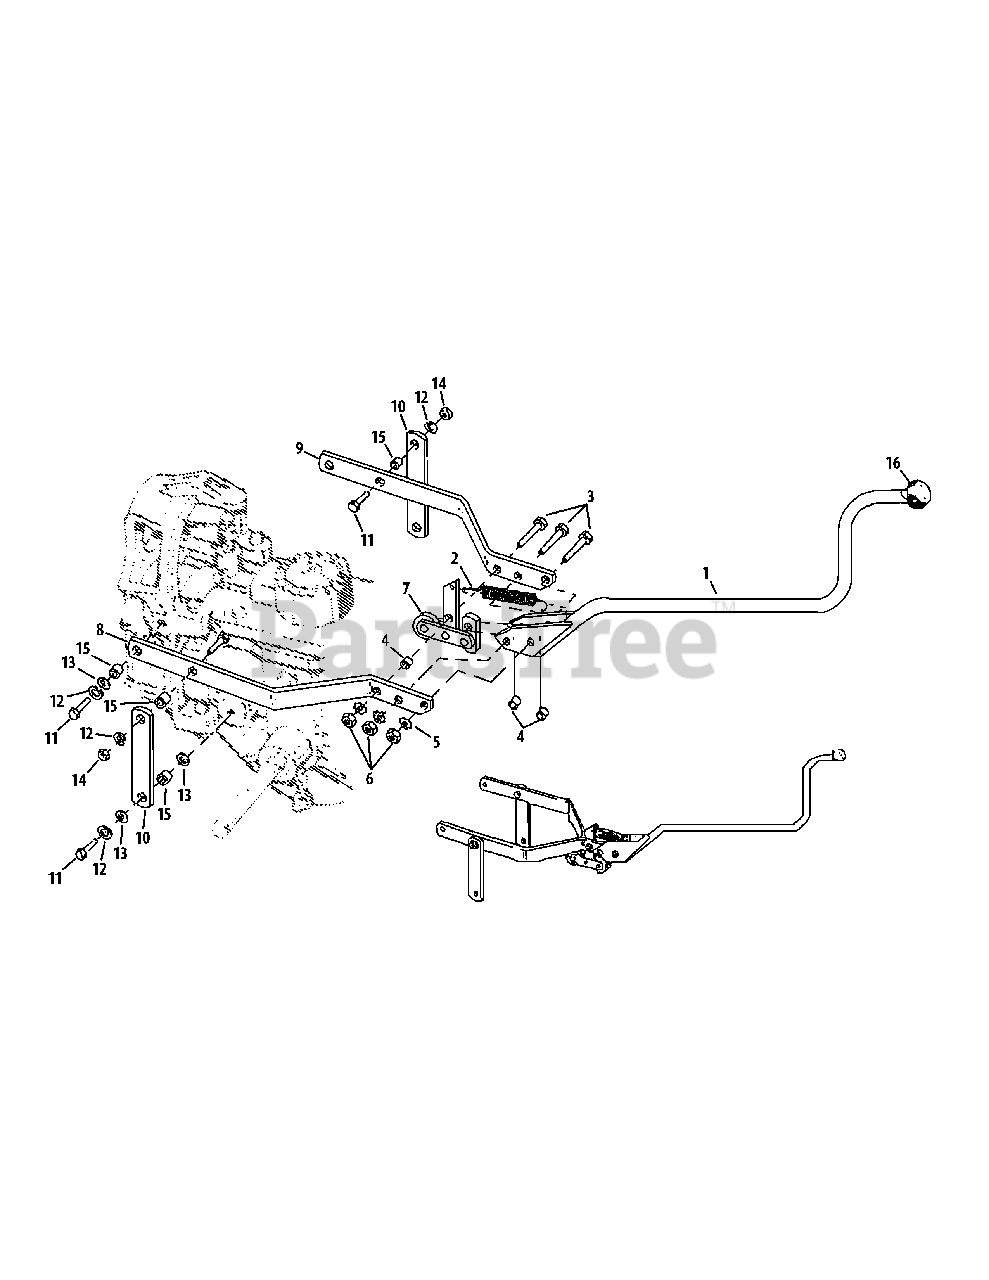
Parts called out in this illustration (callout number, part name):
1	Forward/Reverse Lever
2	Clutch Pawl Spring
3	Hex Bolt, 5/16"-18 x 1-1/2"
4	Bushing, .5 x .316 x .375
5	External Tooth Lockwasher, 5/16"
6	Hex Nut, 5/16"-18
7	Roller Assembly
8	Yoke (Left)
9	Yoke (Right)
10	Yoke Pivot Link
11	Hex Bolt, 3/8"-16 x 1"
12	Lockwasher, 3/8"
13	Flat Washer, 3/8"
14	Hex Nut, 3/8"-16
15	Bushing Spacer, .5 x .375 x .3
